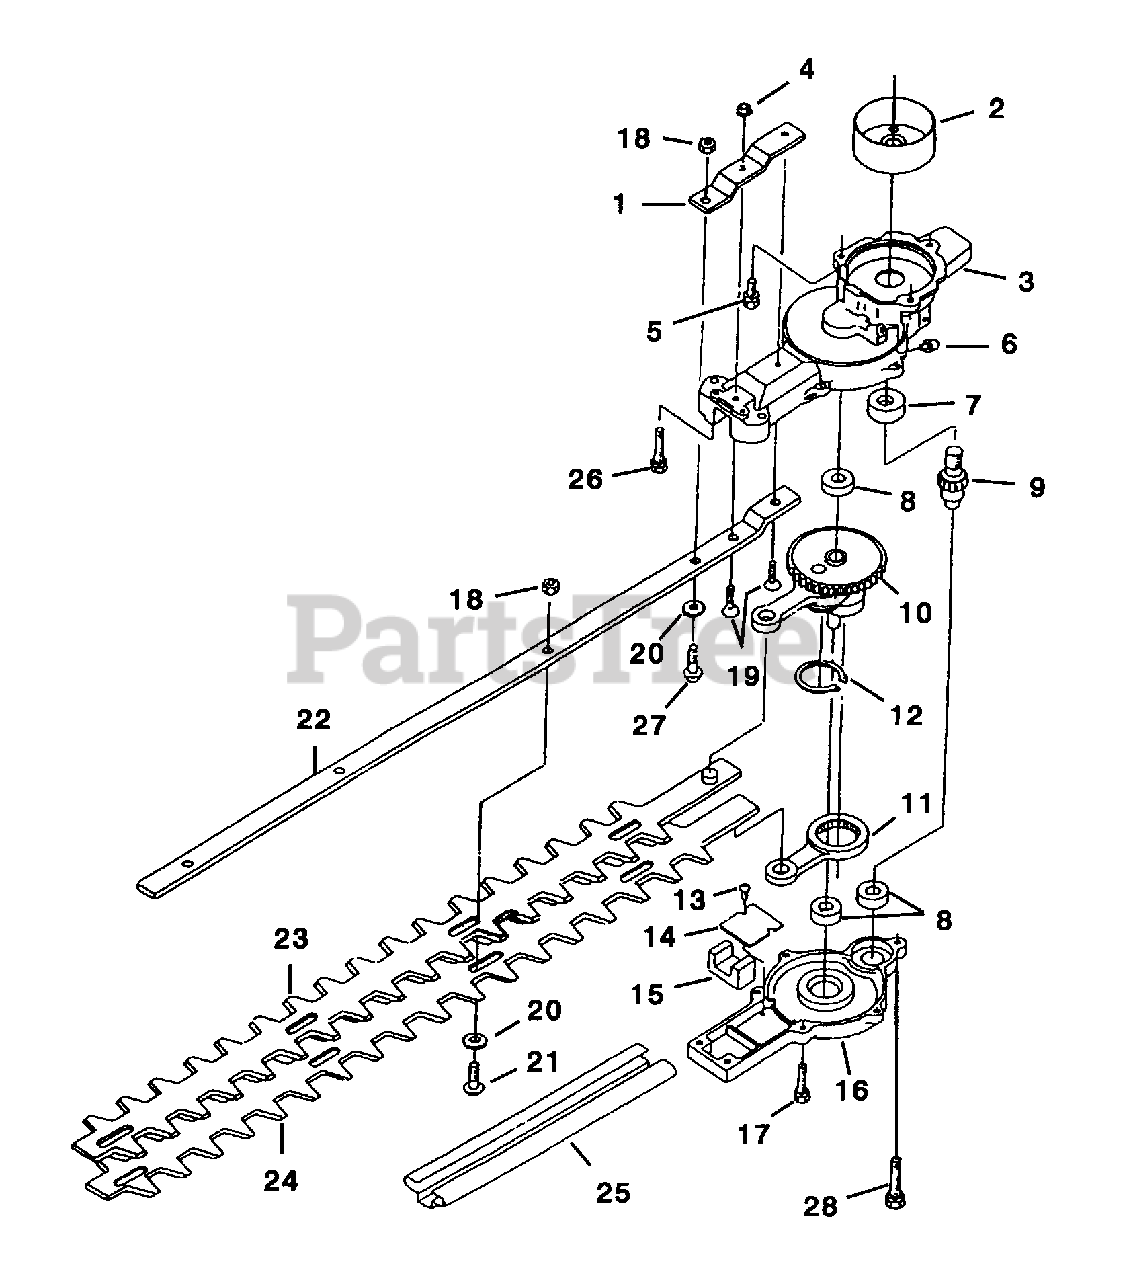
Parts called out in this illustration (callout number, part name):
1	REINFORCING PLATE
2	DRUM-Clutch
3	CASE-Upper
4	FLANGE NUT (M5)
5	BOLT (M6 x 15 W SW)
6	NIPPLE-Grease (M6)
9	GEAR-Pinion
10	GEAR-Crank
12	SNAP RING
13	SCREW (M3 x 5)
14	PLATE-Rod Slide
16	CASE-Lower
17	BOLT (M5 x 16 W SW)
18	U-NUT (M6)
19	SCREW (M5 x 20)
20	WASHER-Blade Side
21	SCREW (L-19)
22	GUIDE PLATE
23	BLADE-Upper
24	BLADE-Lower
25	COVER-Blade
26	SCREW (M6 x 35 W SW & PW)
27	SCREW (L-22)
28	SCREW (M6 X 40 W SW & PW)
